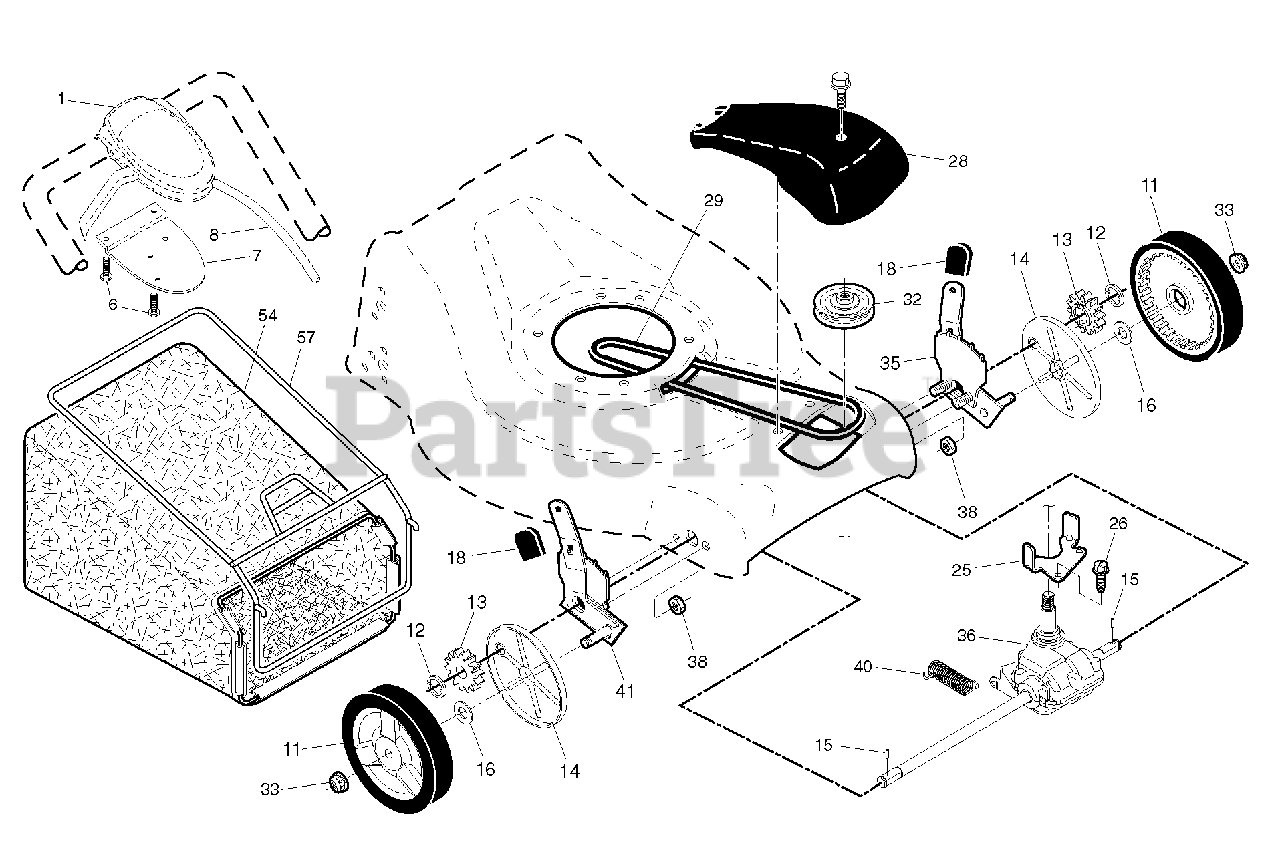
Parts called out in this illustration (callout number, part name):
1	CONTROL.DR.QW.21FGD.BS.GY/BLK
6	SCREW, PHILLIPS HEAD 10 X 5/8
7	BRACKET.DRIVE.CONTROL.MOUNT.BL
8	CABLE ASSEMBLY, DRIVE
11	WHEEL.8X1.75.H3SPK.RAD3.GY.BU3
12	E-RING 7/16 RE
13	PINION.14.TEETH.FGD
14	COVER.DUST.WHEEL.INNER.WALK
15	PAWL, DRIVE
16	WASHER FLUT
18	SELECTOR KNOB
25	BRACKET.BELT.GUIDE.22+FGD.BZP
28	COVER.DR.ASM.181468.CE
29	BELT.DRIVE.FG
32	PULLEY.DRIVEN.EZ/VARI (2 2MC)
33	NUT.HEX.FLANGE.3/8-16.LO(3 2)
35	ADJUSTER.ASSEM.LEFT.FGD.WALK
36	TRANSMISSION.21.FGD.HT.VST
38	LOCKNUT.NYLOC.1/4-20
41	ADJUSTER.ASESM.RIGHT.FGD.WALK
54	GBAG.34710090.H-GREY MS498
57	FRAME.GBAG.21.FWGD
